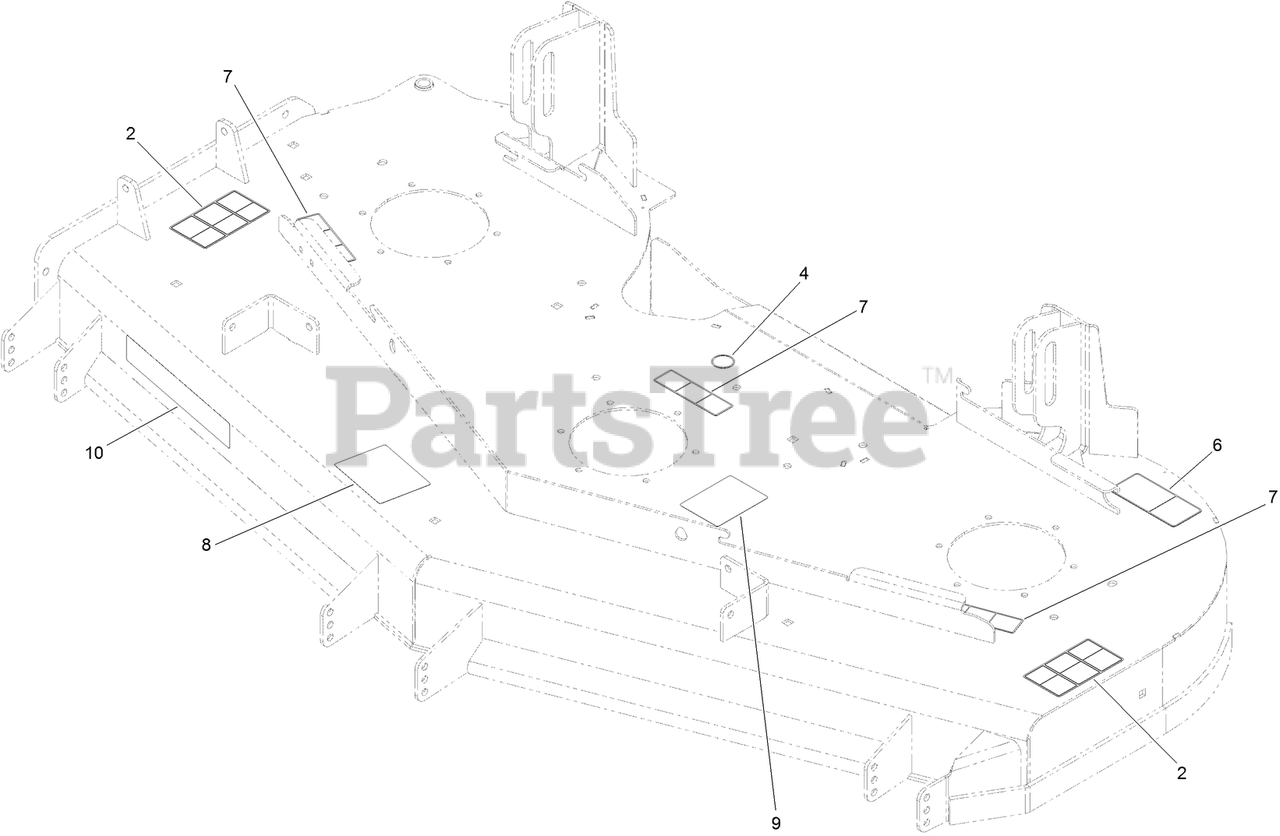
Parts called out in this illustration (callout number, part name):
2	DECAL-DANGER
4	DECAL-GREASE
6	DECAL-TORQUE, BLADE BOLT
7	DECAL-MISSING, COVER
8	DECAL-SCALP, ANTI
9	DECAL-ROUTING, DECK BELT
